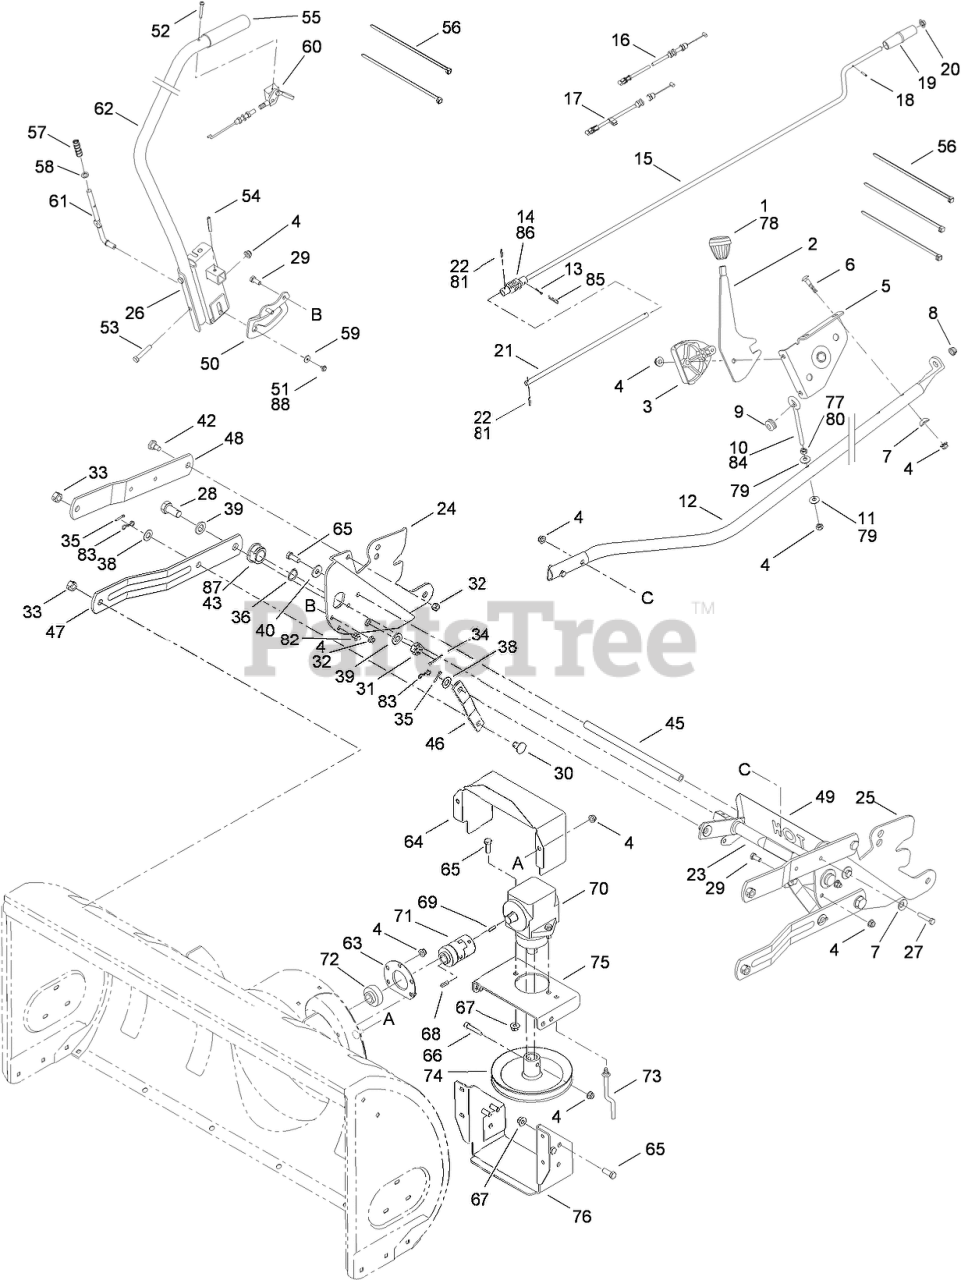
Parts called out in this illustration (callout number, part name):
2	HANDLE-TILT, CHUTE
3	GUIDE-CABLE
4	NUT-LOCK, FLANGE
5	BRACKET-TILT, CHUTE
6	BOLT-CARR
7	WASHER-SADDLE
8	BUSHING
9	GROMMET
10	EYEBOLT
11	WASHER-BELL
12	TUBE-SUPPORT, CHUTE
13	PIN-COTTER
14	JOINT BLOCK ASM
15	ROD-CRANK, CHUTE
16	CABLE-CHUTE
17	CABLE-CHUTE
18	PIN-ROLL
19	KNOB-CRANK, CHUTE
20	NUT-PUSH
22	PIN-SPRING, SPIRAL
23	ROD ASM
24	RH SUPPORT PLATE ASM
25	LH SUPPORT PLATE ASM
26	LIFT BRACKET ASM
27	SCREW-HH
28	SCREW-HH
29	SCREW-HH
30	PIN-BRACKET, LIFT
31	NUT-HEX CASTLE
32	NUT-LOCK
33	NUT-HEX, LOCK
34	PIN-COTTER
35	PIN-COTTER
36	RING-SNAP
38	WASHER-FLAT
39	WASHER-FLAT
40	WASHER-BELL
42	BOLT-SHOULDER
43	BEARING-FLANGE
49	SHIELD-HEAT
50	BRACKET-LIFT
51	SCREW-HH, TAP
52	SCREW-PAN HD
53	BOLT-HH
54	PIN-ROLL
56	TIE-CABLE
57	SPRING-COMPRESSION
58	WASHER-FLAT
59	WASHER-FLAT
60	CABLE-LIFT, W/TRIGGER
61	ROD-INDEX, LIFT
62	TUBE-HANDLE, LIFT
63	HOUSING-BEARING
64	COVER-BELT
65	SCREW-HH
66	SCREW-HSH
67	NUT-LOCK, FLANGE
68	KEY-SQUARE
69	KEY-HI PRO
70	DRIVE-ANGLE, RIGHT
71	COUPLER-FLEXIBLE
72	BEARING-BALL (W/OUT COLLAR)
73	ROD-KEEPER, BELT
74	PULLEY-DRIVE
75	BRACKET-MOUNTING
76	PLATE-SKID
77	NUT-HEX
79	WASHER-SPRING
80	NUT-HEX
81	PIN-SPIROL
82	SCREW-HWH
83	PIN-COTTER, BOW TIE
84	BOLT-EYE
85	PIN-COTTER
86	JOINT BLOCK ASM
87	BEARING-FLANGE
88	SCREW-WASHER, HEX INDEX
